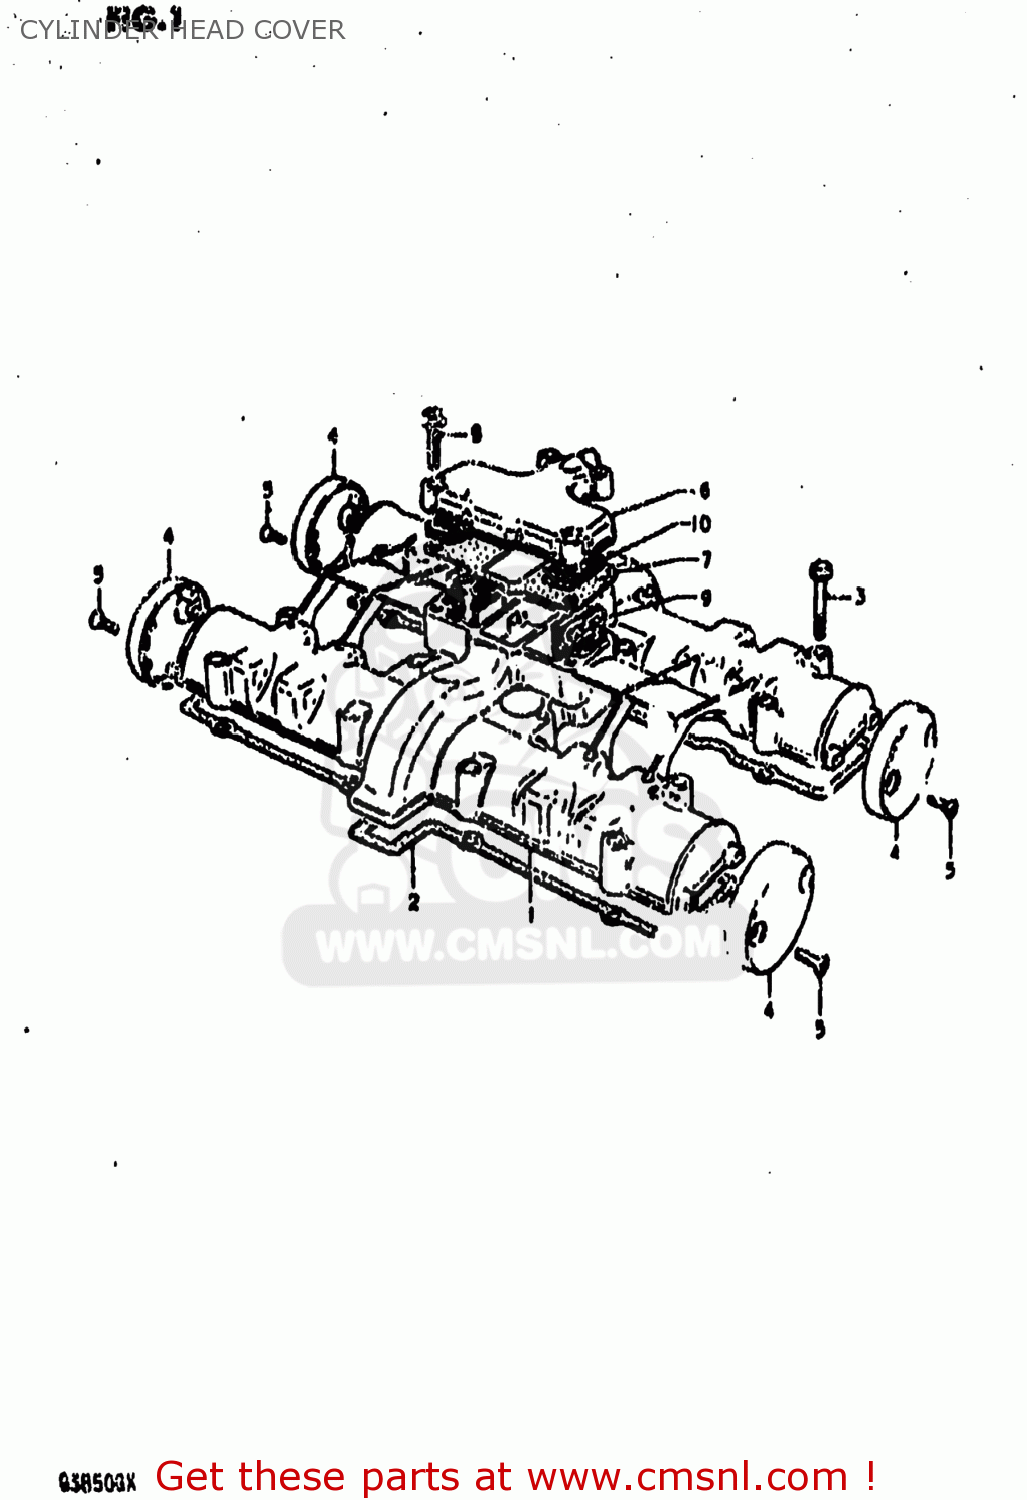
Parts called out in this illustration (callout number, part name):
1	COVER,CYLINDER HEAD
2	GASKET,CYLINDER HEAD COVER (MCA)
3	BOLT
4	CAP,CYLINDER HEAD COVER
5	SCREW 5X12
6	COVER,BREATHER
7	GASKET (MCA)
8	BOLT
9	COVER,BREATHER
10	SEPARATOR,OIL BREATHER
